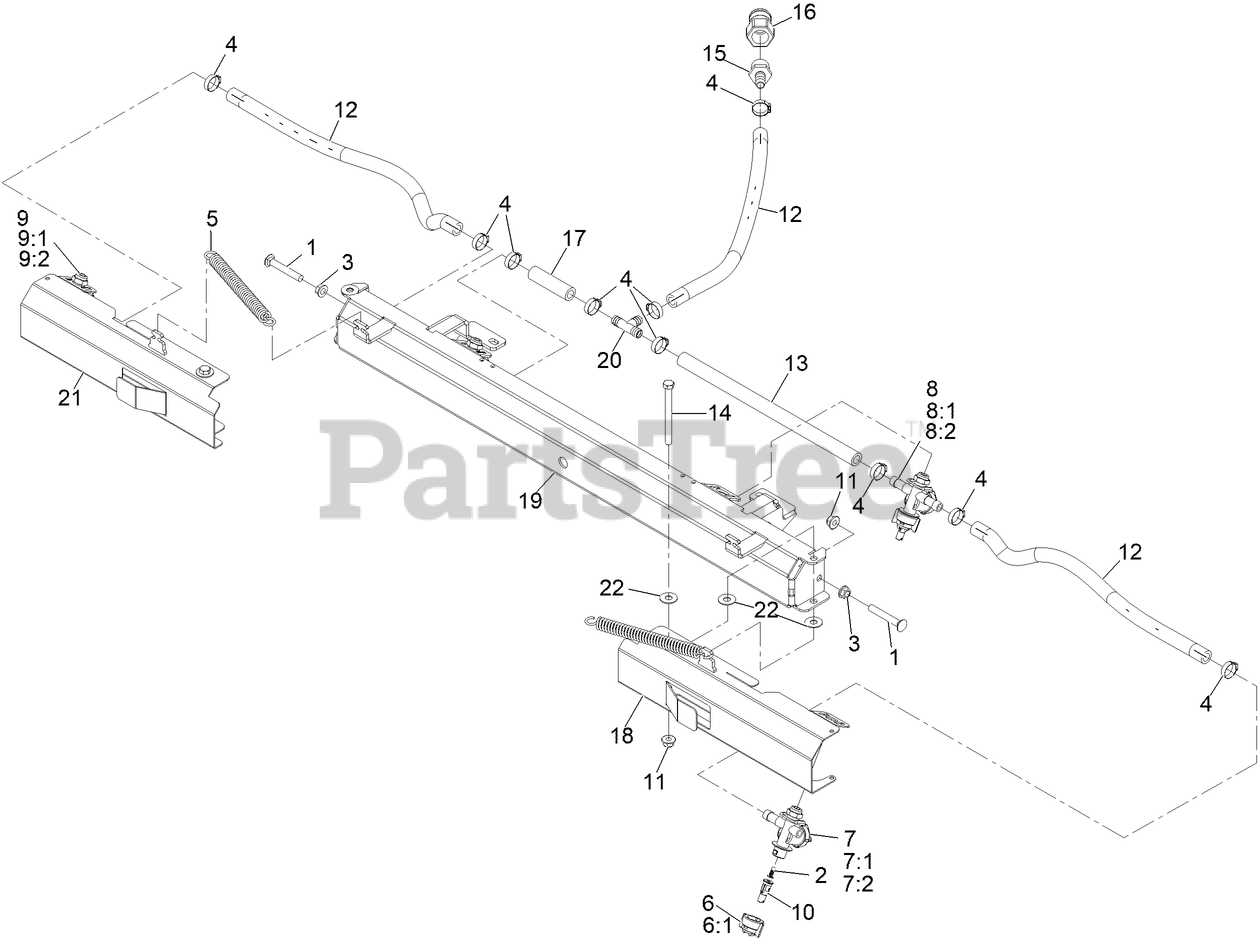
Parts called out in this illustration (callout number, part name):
1	SCREW-CARR
2	STRAINER-NOZZLE, 50M 5PSI
4	CLAMP-OETIKER, 167
5	SPRING-EXTENSION
6	CAP-NOZZLE
6:1	SEAT-GASKET
7	BODY-NOZZLE, LEFT
7:1	CAP-DIAPHRAM
7:2	DIAPHRAGM FOR CHECK VALVE
8	BODY-NOZZLE, CENTER
8:1	DIAPHRAGM FOR CHECK VALVE
8:2	CAP-DIAPHRAM
9	BODY-NOZZLE, RIGHT
9:1	CAP-SPRAYER NOZZLE
9:2	DIAPHRAGM-SPRAYER NOZZLE
10	TIP-SPRAY, 025
11	Nut-Hex Flange
12	HOSE-SPRAY
13	HOSE-SPRAY
14	SCREW-HH
15	FITTING-STRAIGHT
16	ADAPTER-MALE
17	HOSE-SPRAY
18	WING-BOOM LH
19	WLD, BOOM, CENTER, ZPLUG
20	FITTING-TEE, BARB
21	WING-BOOM RH
22	WASHER-FLAT
